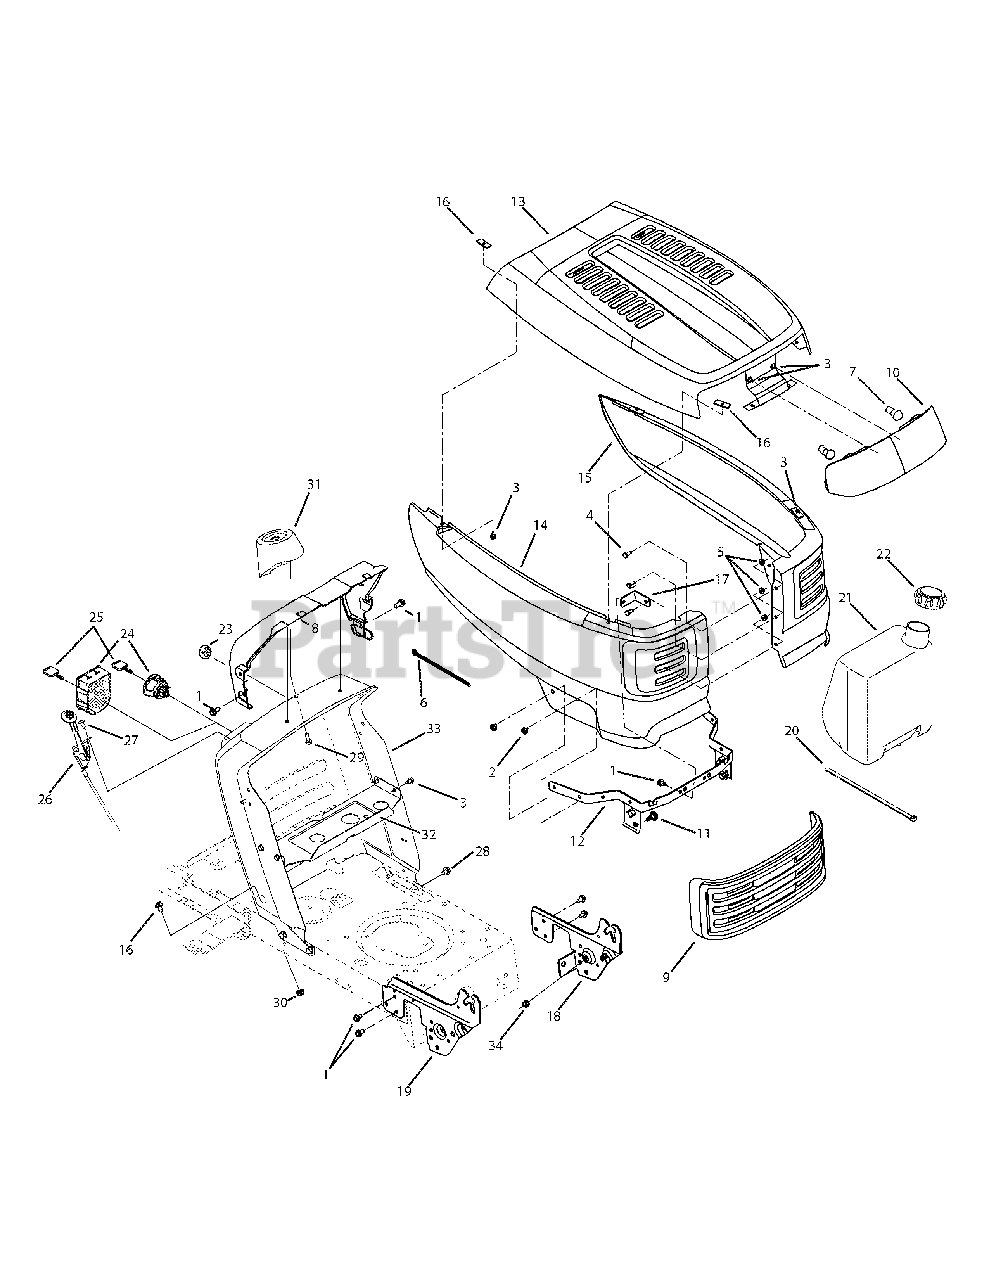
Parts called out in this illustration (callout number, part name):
1	Screw, 5/16-18, 0.750
2	Screw, 5/16-18, 0.375
3	Screw, 1/4-20, 0.500
4	Screw, 1/4-20, .620, Gr5
5	Nut, Flange Lock, 1/4-20, Gr5
6	Cable Tie, 3/16 x .05 x 7.4
7	Headlamp, 12V
9	T-Style Grill Insert
10	Lens, T-Style
11	Screw, Shldr, .43 x .29, 5/16-18
16	Hood Fastener, T-Style
20	Cable Tie, 34.75
21	Fuel Tank, 1.5 gal.
22	Fuel Tank Cap
24	Igntion, Switch (No RMC) 3 Position
25	Key
26	Throttle/Choke Control, 25.0
27	Screw, 1/4-14, .500
28	Screw, 5/16-18, 0.625
29	Screw, 1/4-15, 0.750
30	Flange Lock Nut 5/16-18
31	Support, Steering
